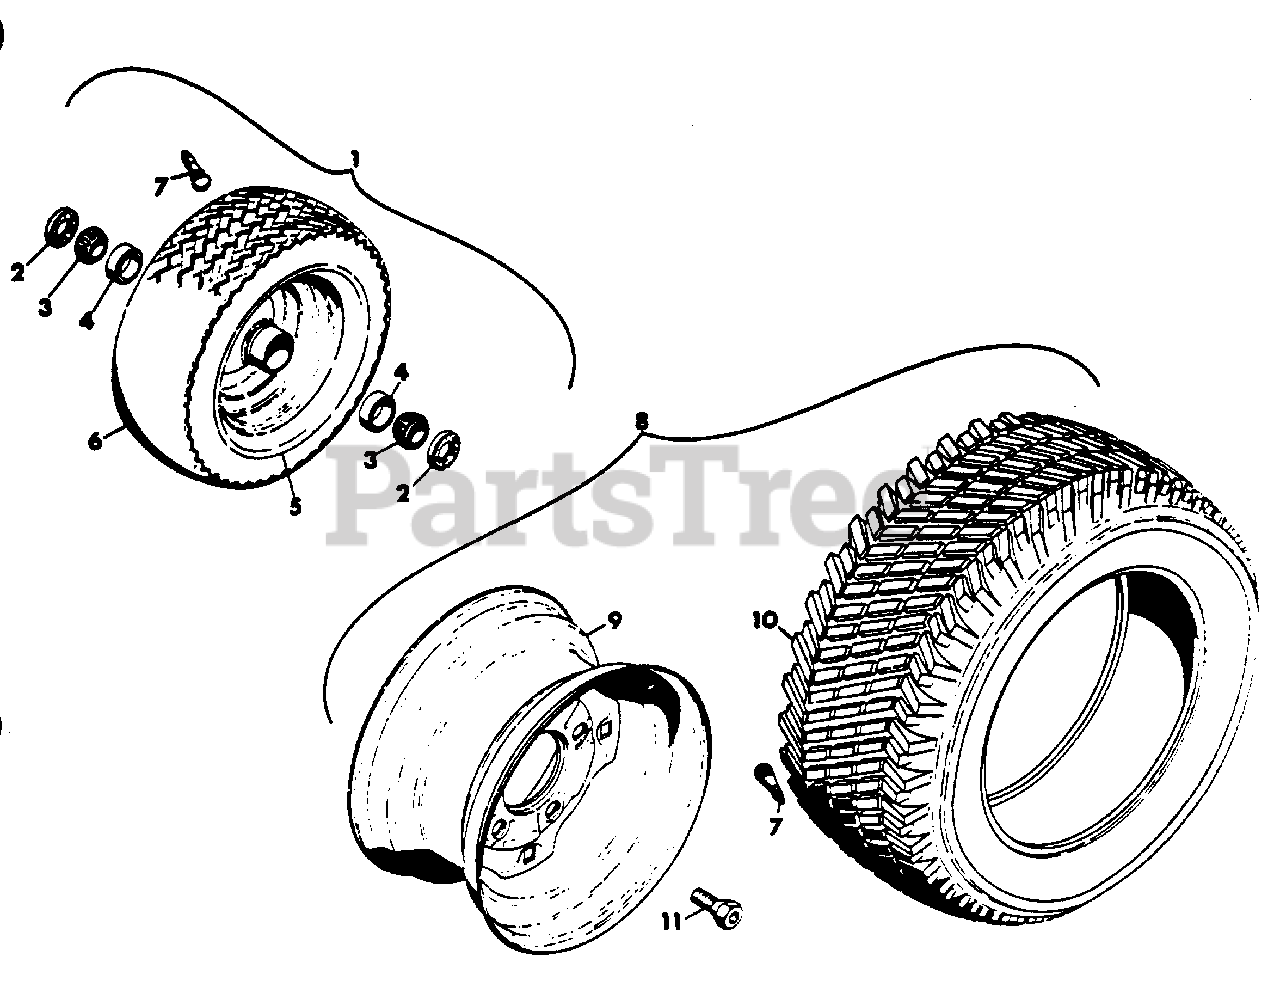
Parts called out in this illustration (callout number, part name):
1	WHEEL, PRO MASTER REAR
2	SEAL, WHEEL
3	BEARING, CONE
4	BEARING, CUP
5	RIM, REAR
6	TIRE, 16X4.80-8
7	ASSEMBLY, VALVE STEM
8	WHEEL, PRO MASTER FRONT
9	RIM, PRO MASTER-50
10	TIRE, 20X10.00-10
11	STUD, WHEEL
